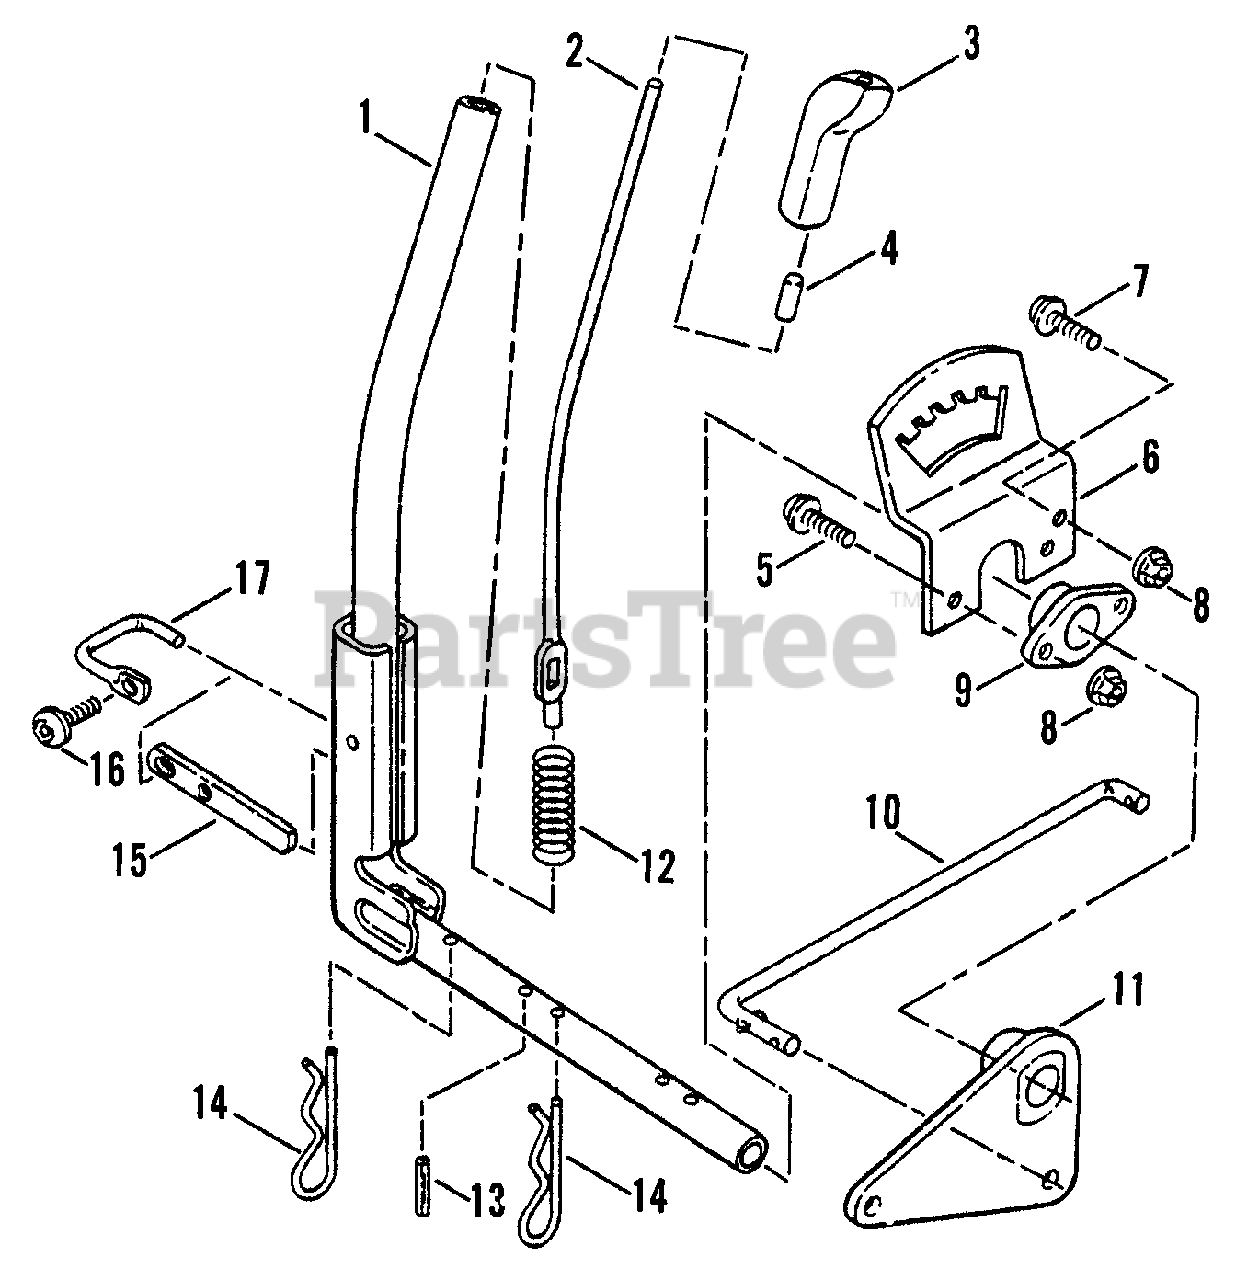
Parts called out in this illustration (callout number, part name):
1	STRUCTURE, Lift Lever
2	ROD, Lift Lever
3	KNOB, Lift Lever
4	CAP, Lever Rod
5	SCREW, 5/16-18 x 7/8" Truss Head (Torx)
6	QUADRANT, Lift Lever
7	SCREW, 5/16-18 x 5/8" Truss Head (Torx)
8	NUT, 5/16-18 Hex Flange Lock
9	PIVOT, Lift Lever
10	ROD, Lift Link
11	BELLCRANK, Lift Structure
12	SPRING, Lift Lever Rod
13	PIN, 1/4 x 1 1/8" Dowel
14	PIN, 5/32 x 2 5/8" Hair
15	DETENT, Latch
16	SCREW, 1/4-20 x 5/8" Truss Head (Torx)
17	LATCH, Pivot
